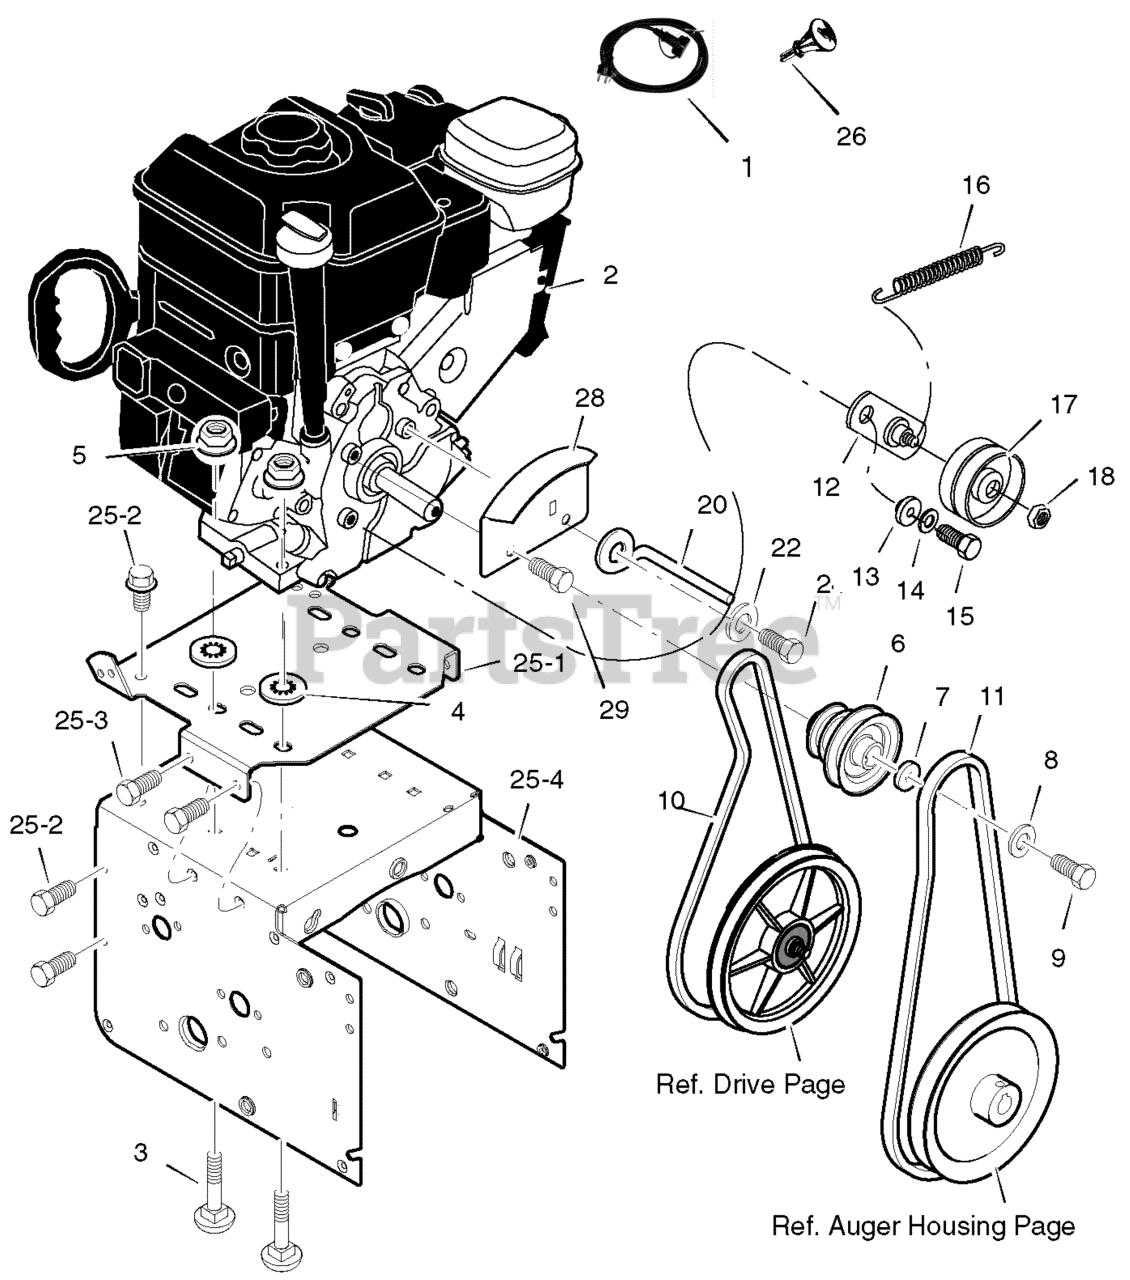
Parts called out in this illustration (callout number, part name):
1	CORD, ELECTRIC
2	ENGINE
3	BOLT, CARRIAGE
4	RETAINER, PUSH
6	PULLEY, ENGINE
7	WASHER
8	WASHER
9	SCREW
10	BELT, DRIVE V 3L
11	BELT, AUGER V 4L
12	BRACKET ASSEMBLY, IDLER
13	BUSHING, IDLER BRACKET
14	WASHER, SPLIT
15	SCREW 5/16-24 X 0.75
16	SPRING, IDLER TRACTION DRIVE
17	PULLEY, IDLER
18	NUT, JAM 3/8-16
20	GUIDE, ROD BELT
22	WASHER
25	FRAME ASSEMBLY
25-1	PLATE, ENGINE
25-2	SCREW
25-3	SCREW
25-4	MOTOR BOX
26	KEY, ENGINE
28	BRACKET, ENGINE SHIELD
